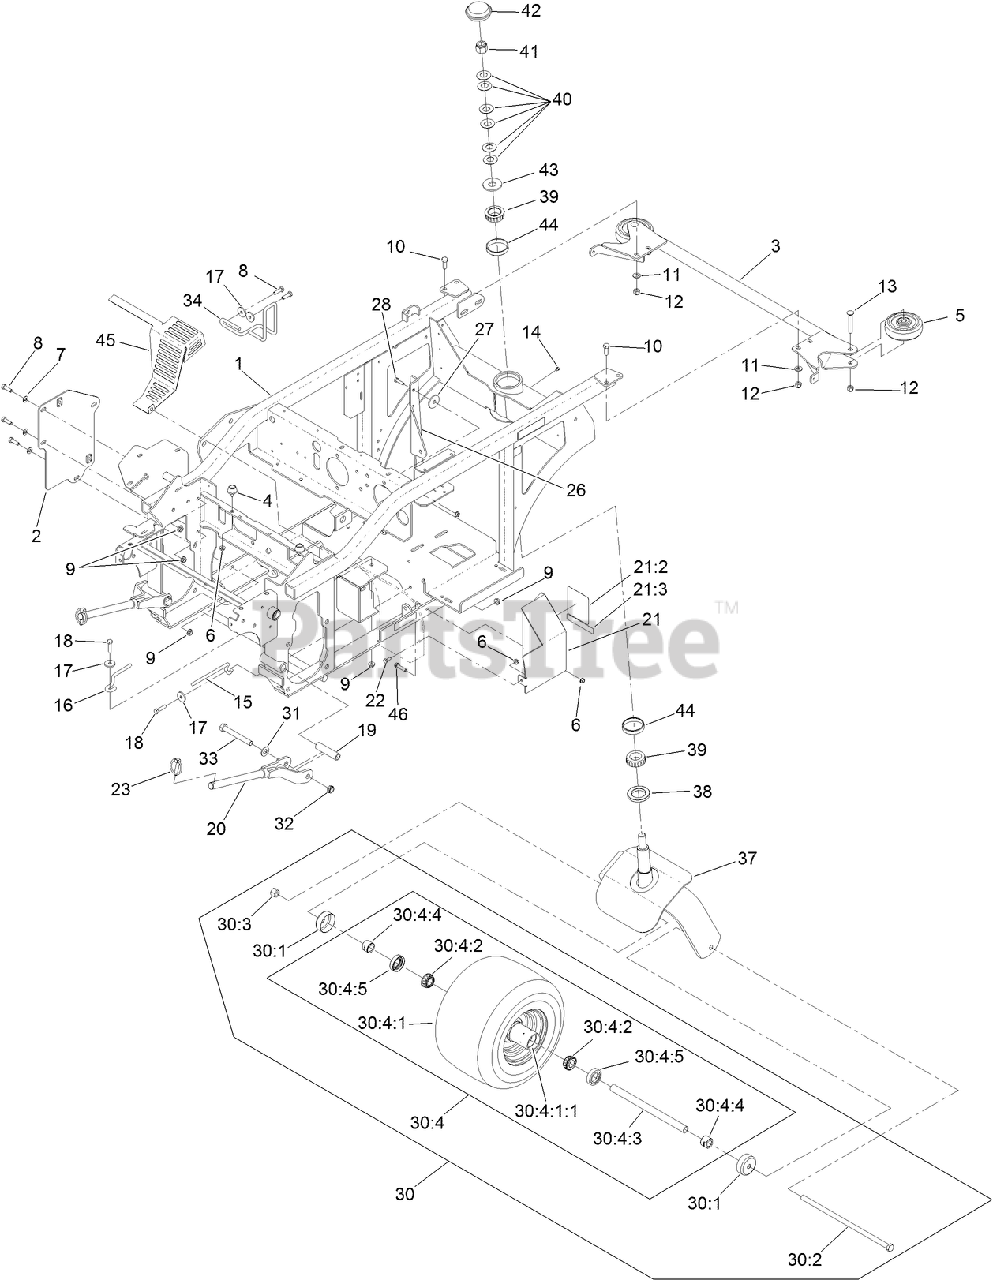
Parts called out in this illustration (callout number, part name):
1	FRAME ASM
2	PLATE-SUPPORT
3	BUMPER-REAR
4	BUMPER-RUBBER
5	ROLLER-BUMPER
6	NUT-HF
7	WASHER-PLAIN
8	SCREW-HH
9	NUT-HF
10	SCREW-HH
11	WASHER-FLAT
12	NUT-LOCK, NI
13	SCREW-CARR
15	GUIDE-BELT
16	GUIDE-BELT
17	WASHER
18	SCREW-HH
19	SPACER-WHEEL, SHORT
20	ROD-PUSH
21	SHIELD ASM-DRIVE
21:2	DECAL-BELT ROUTING
21:3	DECAL-WARNING
22	SCREW-HH
23	PIN-LYNCH
26	BRACE-PTO
27	WASHER
28	SCREW-HH
30	WHEEL AND AXLE ASM
30:1	GUARD-SEAL
30:2	SCREW-HH
30:3	NUT-LOCK, NI
30:4	WHEEL AND BEARING ASM
30:4:1	Deck ASM
30:4:1:1	BEARING-CUP
30:4:2	BEARING-CONE, TAPER
30:4:3	AXLE CASTER ASM
30:4:4	SPACER-NUT
30:4:5	SEAL-CASTER
31	WASHER-FLAT
32	NUT-HEX
33	SCREW-HH
34	GUIDE-BELT
37	FORK-REAR CASTER
38	SEAL-GREASE
39	BEARING-ROLLER, CONE TAPER
40	WASHER-BELLVILLE
41	NUT-LOCK, NI
42	CAP-GREASE
43	WASHER-FLAT
44	CUP-TAPERED, ROLLER BEARING
45	SHIELD-HEAT
46	SCREW-HHF
